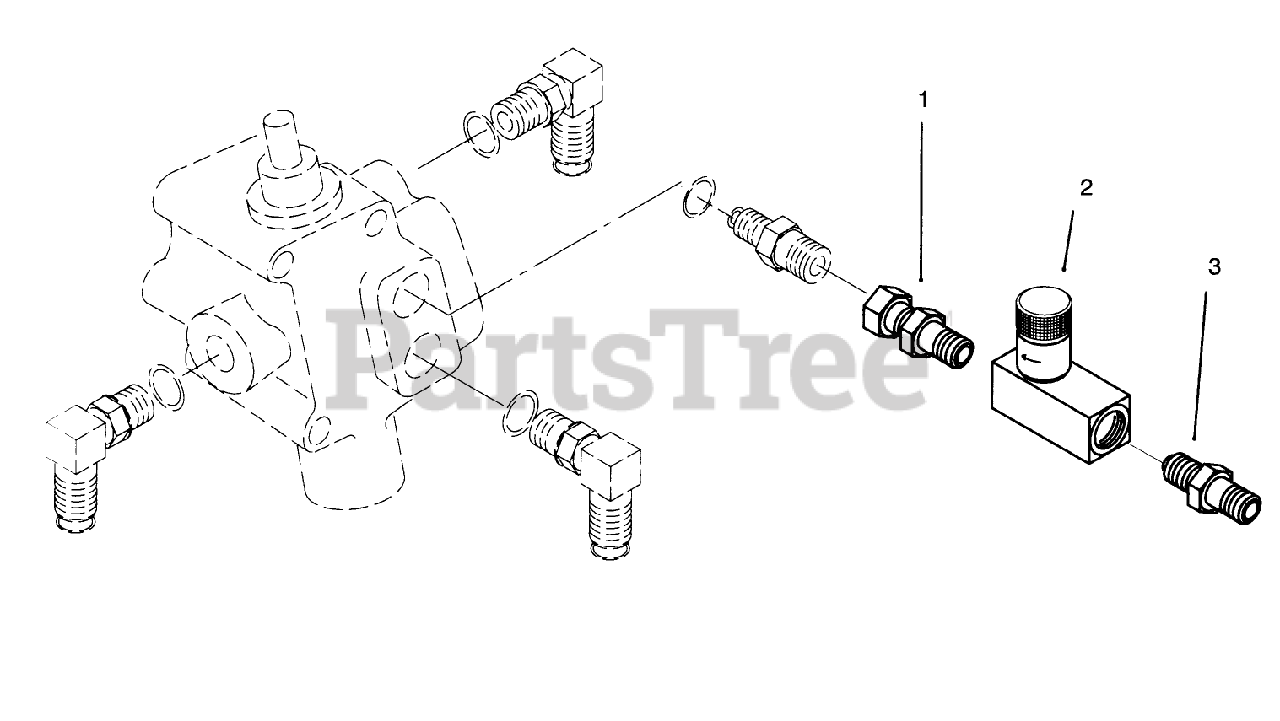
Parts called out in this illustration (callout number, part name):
1	FITTING-SWIVEL STRAIGHT
2	VALVE-ADJUSTABLE FLOW
3	FITTING-MALE
